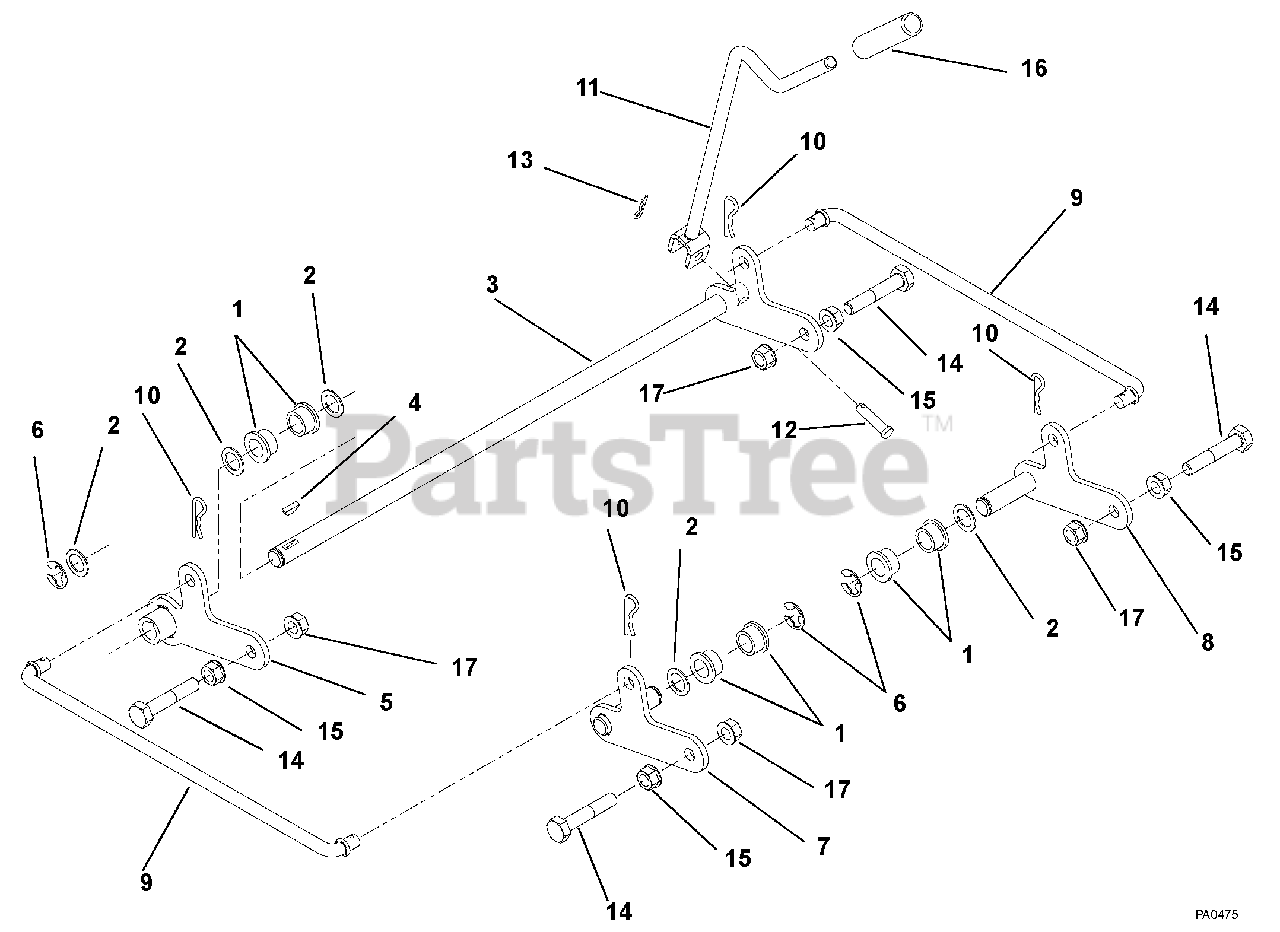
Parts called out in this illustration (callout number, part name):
1	BSHG-FLG .750X1.000X.625X1.250
2	WSHR-FL-STL.754X1.125X.062YWZC
3	WMT, DECK LIFT CROSS SHAFT
4	KEY-WDRF .188X.75X.313 SAE 9
5	WMT, KEYED DECK LIFT ARM
6	RG-RTNG-EXT .750X.050
7	WELDMENT, DECK LIFT ARM-RH
8	WELDMENT, DECK LIFT ARM-LH
9	ROD,LIFT
10	PIN, HAIR, EXT - #16 YWZC
11	WELDMENT, DECK LIFT HANDLE
12	PIN-CLEV .370X1.50
13	PIN-HAIR INT .08X.18X1.18 YWZC
14	BLT-HEX .50-13X2.75 YZ GR8
15	NUT-SPNLK-FLG .50-13 YWZC
16	GRIP, .475 ID X 4.25 LG
17	@NUT-LK-NYL-FLG .50-13 YWZC
